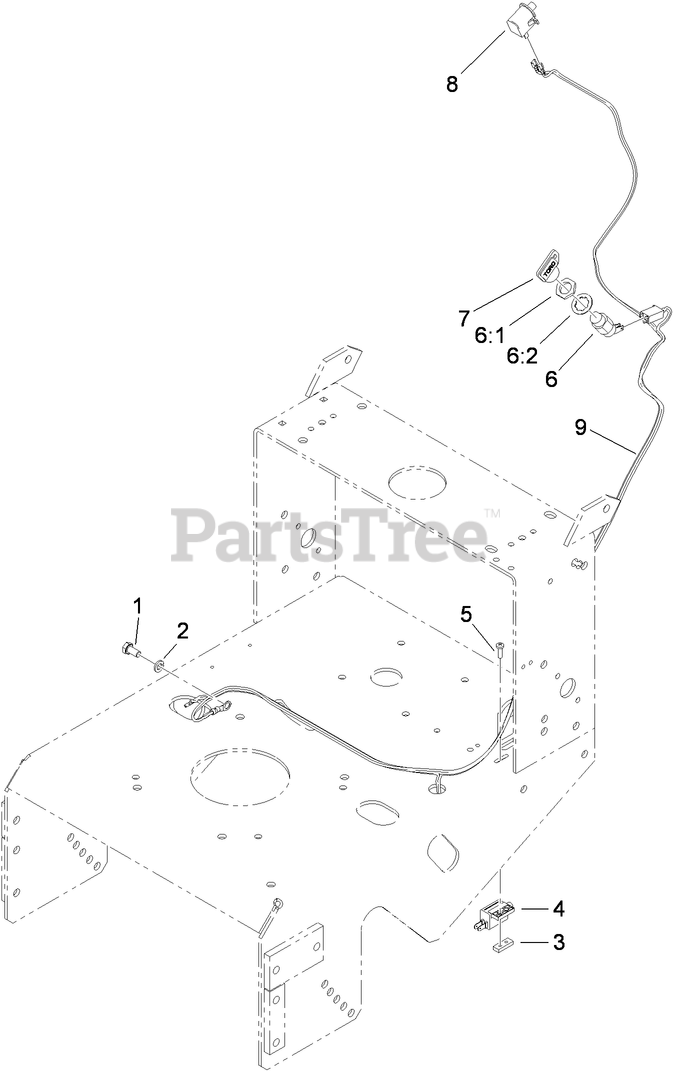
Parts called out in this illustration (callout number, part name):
1	SCREW-HH
2	WASHER-LOCK
3	PLATE-TAPPED
4	SWITCH-CLOSED, NORMALLY
5	SCREW-PPH
6	SWITCH-ON / OFF
6:1	NUT-HH
6:2	WASHER-TOOTH, INTERNAL
7	KEY-IGNITION
8	SWITCH
9	HARNESS-WIRE
